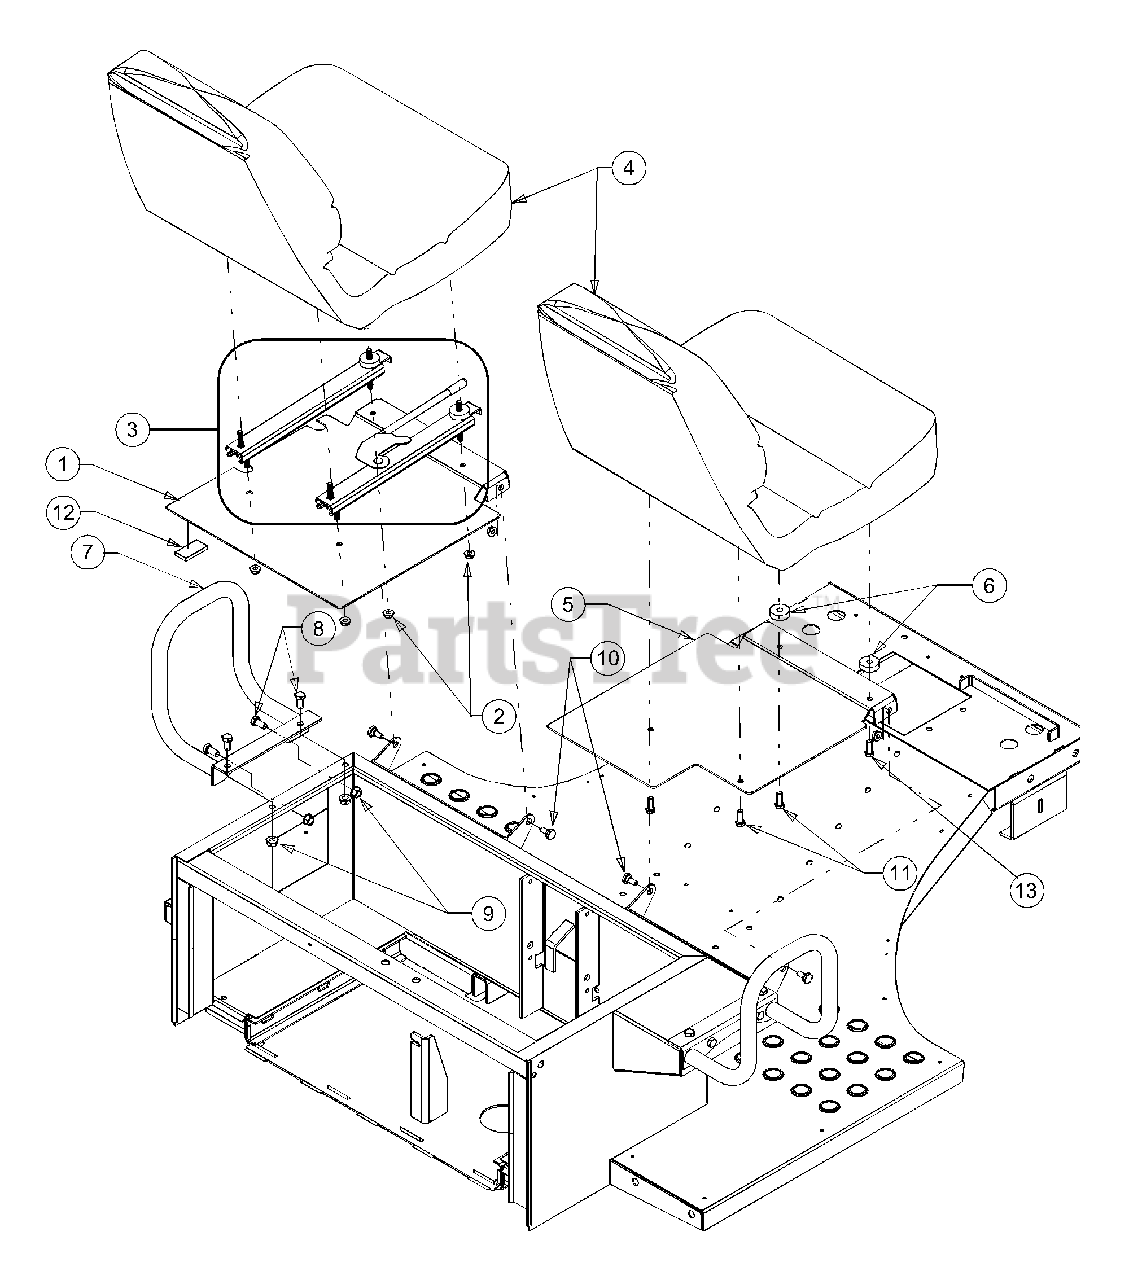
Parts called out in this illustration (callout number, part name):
1	Plate, Seat, LH
2	Nut, Flange Lock, 5/16-18, Gr5
3	Track Assembly, Seat
4	Seat
5	Plate, Seat, RH
6	Spacer, Seat
9	Nut, Flange Lock, 3/8-16
10	Shoulder Screw, .435 x .178-5/16 x .56
11	Hex Screw, 5/16-18 x .625, Gr5
12	Bumper .62 Dia x .3
13	Hex Screw 5/16-18 x 1.00 Gr 5
